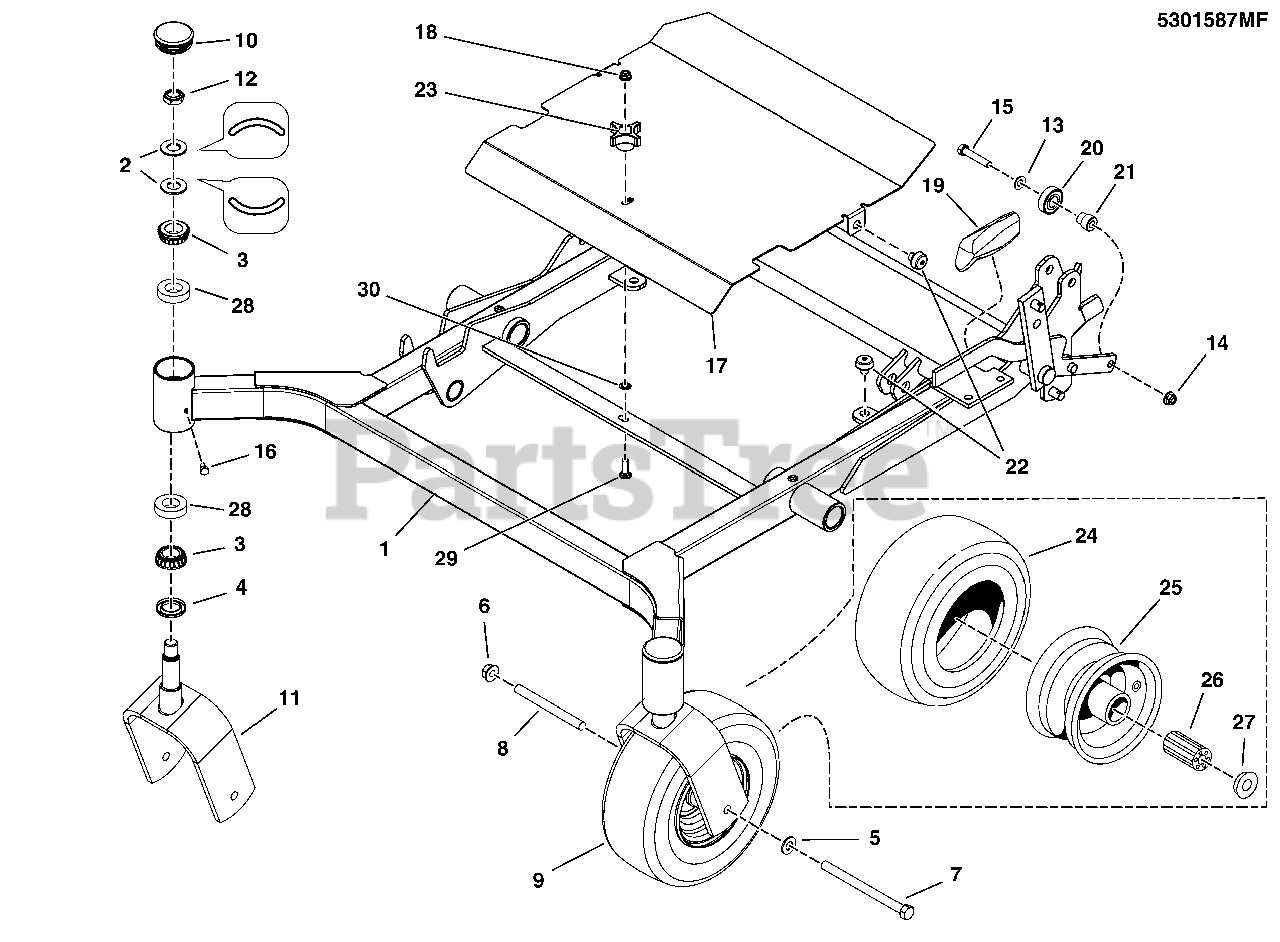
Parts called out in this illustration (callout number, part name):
1	WELD, MOWER FRAME, 800, 61" - RED
2	WASHER, BELLEVILLE - 1.500 X .755
3	BEARING, TAPERED ROLLER, 1
4	SEAL, GREASE
5	WASHER, 1/2 SAE
6	NUT, 1/2-13 HEX NYLOCK FLANGE
7	BOLT, HEX, 1/2-13 X 6-1/2, GD 8, YZ
8	CASTER AXLE DDSH
9	WHEEL, CASTER, 11 X 4.0-5 SILVER BEAD LO
10	CAP, LOW PROFILE, STEEL
11	WELD., FRONT CASTER YOKES - RED
12	NUT, 3/4-16, HEX JAM NYLON LOCK
13	WASHER, 3/8 SAE
14	NUT, 3/8-16 HEX NYLOCK FLANGE
15	BOLT, 3/8-16 X 2 GD5 YZ
16	BOLT, 1/4-28 X 1/2, GD5 YZ
17	DECK GUARD, CENTER, 800, 61" - RED
18	NUT, 5/16-18 HEX NYLOCK FLANGE
19	GRIP, BLACK FLEXIBLE
20	BEARING, BALL 11/16X1-9/16X15/32
21	SPACER, HYDRO PULLEY
22	MNT, VBRTN, RBBR
23	KNOB-INT THR .312-18 4-ARM 2.12 WD 1.06LG
24	TIRE, FRONT, 11 X 4.0 - 5 (SV)
25	WHEEL ASSEMBLY, 11 X 4.0 - 5 TIRE CMP (SV)
26	BEARING, CASTER WHEEL, 11 X 4.0 - 5 BEAD LOCK (SV)
27	BEARING, RETAINER (SV)
28	CUP, BEARING (SV)
29	BOLT, 5/16-18 X 1, CARRIAGE
30	NUT, Push On, 5/16
